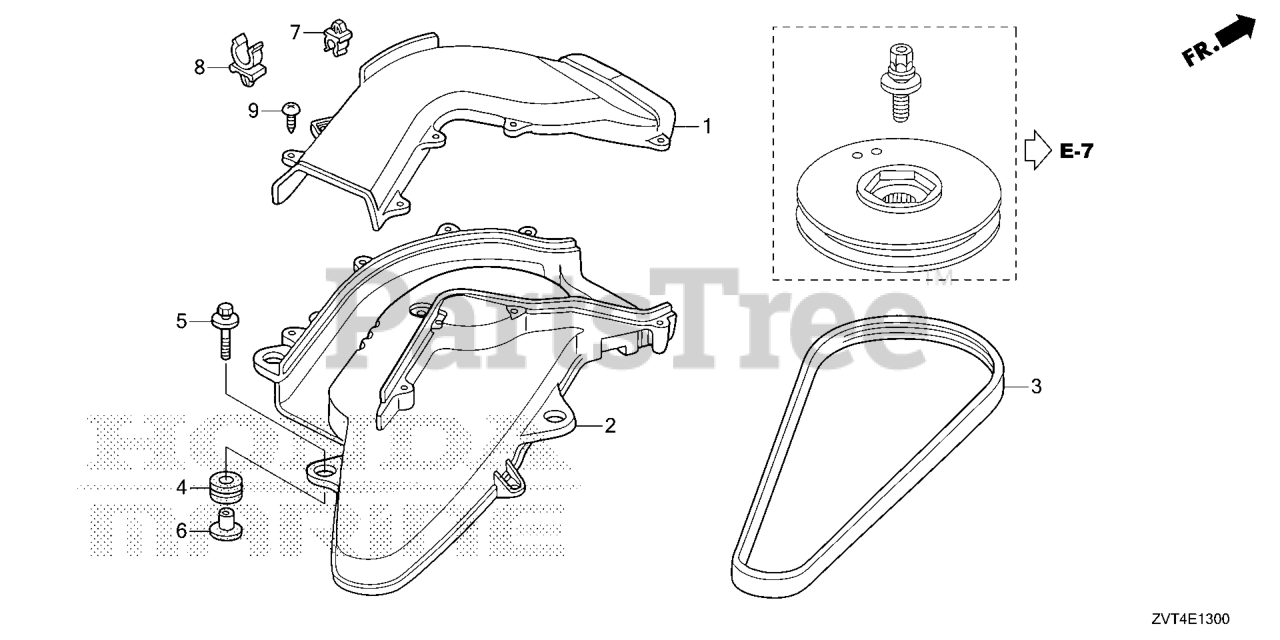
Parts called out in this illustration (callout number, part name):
1	DUCT A, MUFFLER
2	DUCT B, MUFFLER
3	BELT, ALTERNATOR (4PK810)
4	GROMMET, CASE (LOWER)
5	BOLT-WASHER (6X25)
6	COLR, CDI UNIT CASE
7	CLIP, TUBE (3.5)
8	CLAMP (18.5MM)
9	SCREW, TAPPING (5X20)
